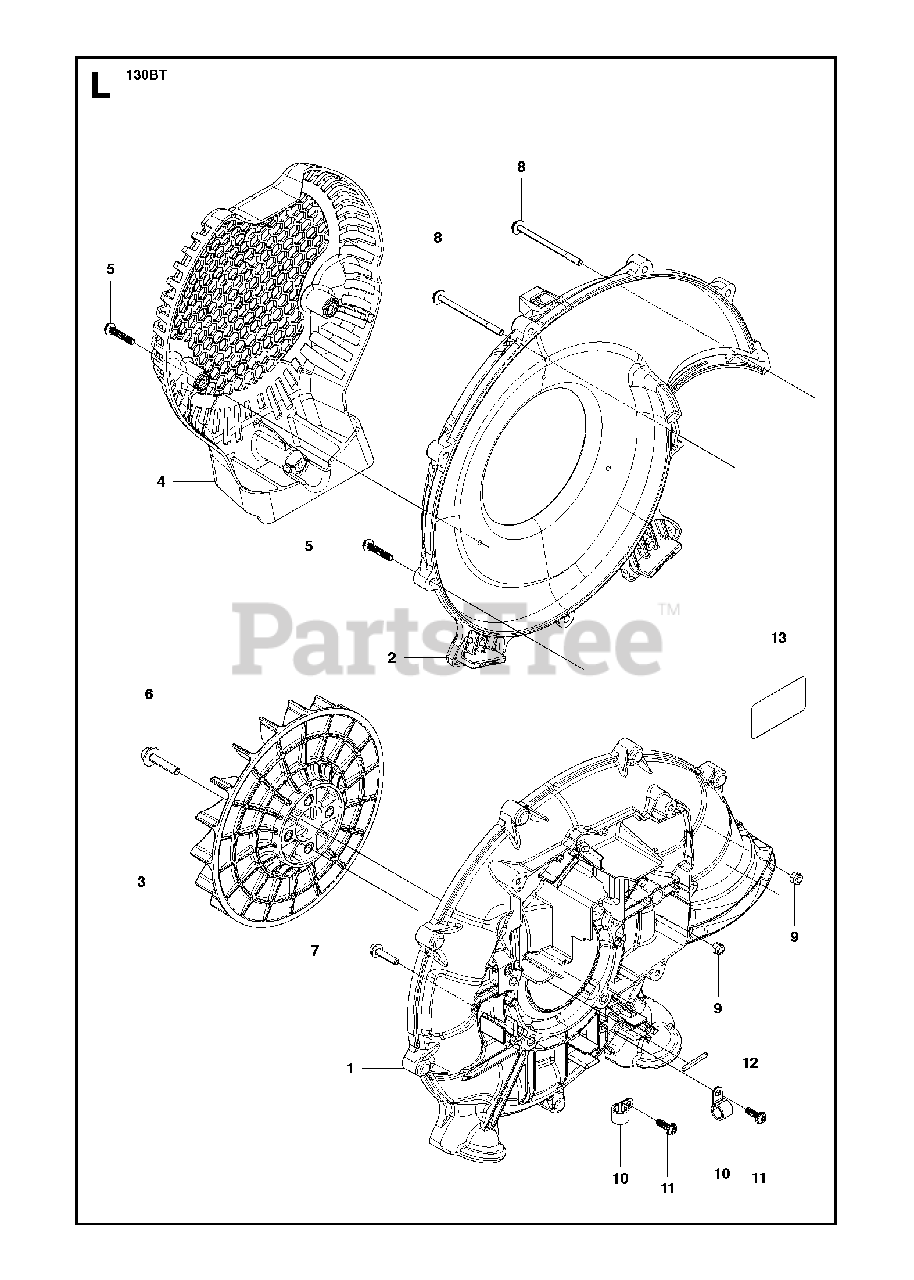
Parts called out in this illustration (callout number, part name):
1	VOLUTE CASE
2	COVER - VOLUTE
12	SEAL 848L2055L0
